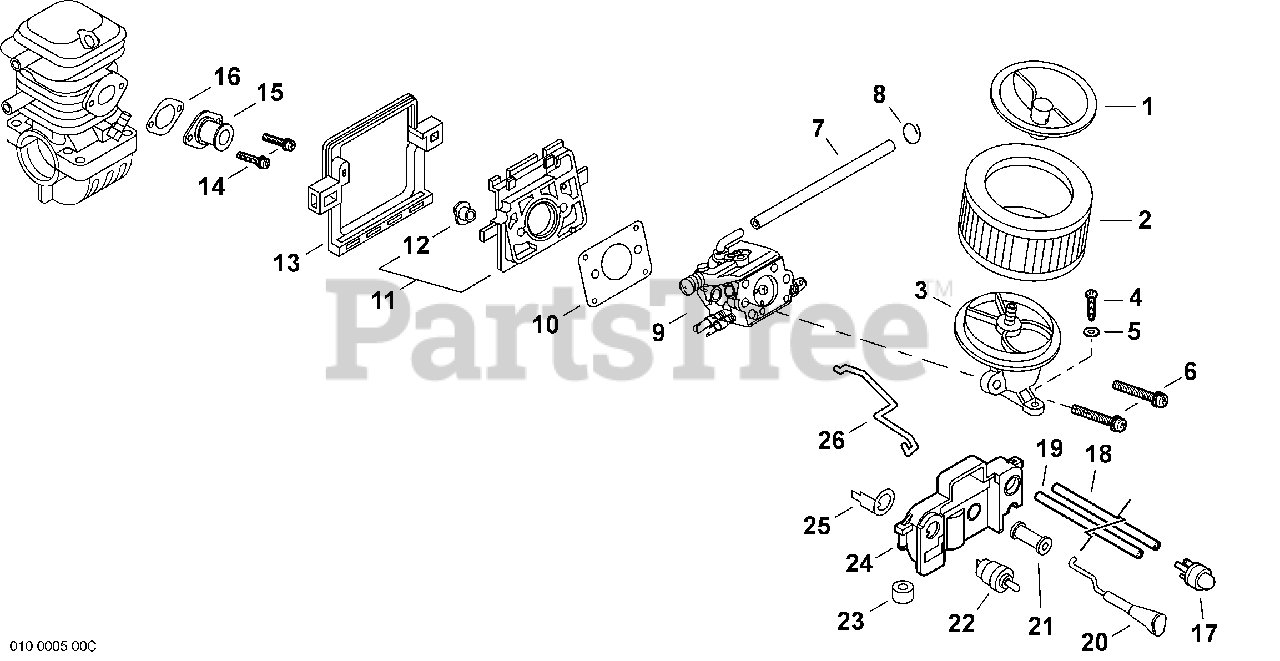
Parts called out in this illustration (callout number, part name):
1	CAP ASSY, AIR FILTER
2	FILTER, HEAVY-DUTY AIR
3	ADAPTOR, INTAKE
4	SCREW, TAPPING 5×20
5	WASHER, FLAT 5.5×10×0.8
6	SCREW 5×50
7	PIPE, PULSE 2.4×6×105
8	CLIP Ø6
9	CARBURETOR - WT-980
10	GASKET, INTAKE
11	INSULATOR KIT, INTAKE
13	CUSHION
14	SCREW 5×14
15	BELLOWS, INTAKE
16	GASKET, INTAKE
17	BULB, PURGE
18	PIPE, FUEL 2.4×5×200 BLACK
19	PIPE 2.4×5×105 BLACK
20	ROD, CHOKE
21	GROMMET, CHOKE
22	SWITCH, ON-OFF
24	BRACKET, SWITCH
25	TERMINAL, GROUND
26	ROD, THROTTLE
